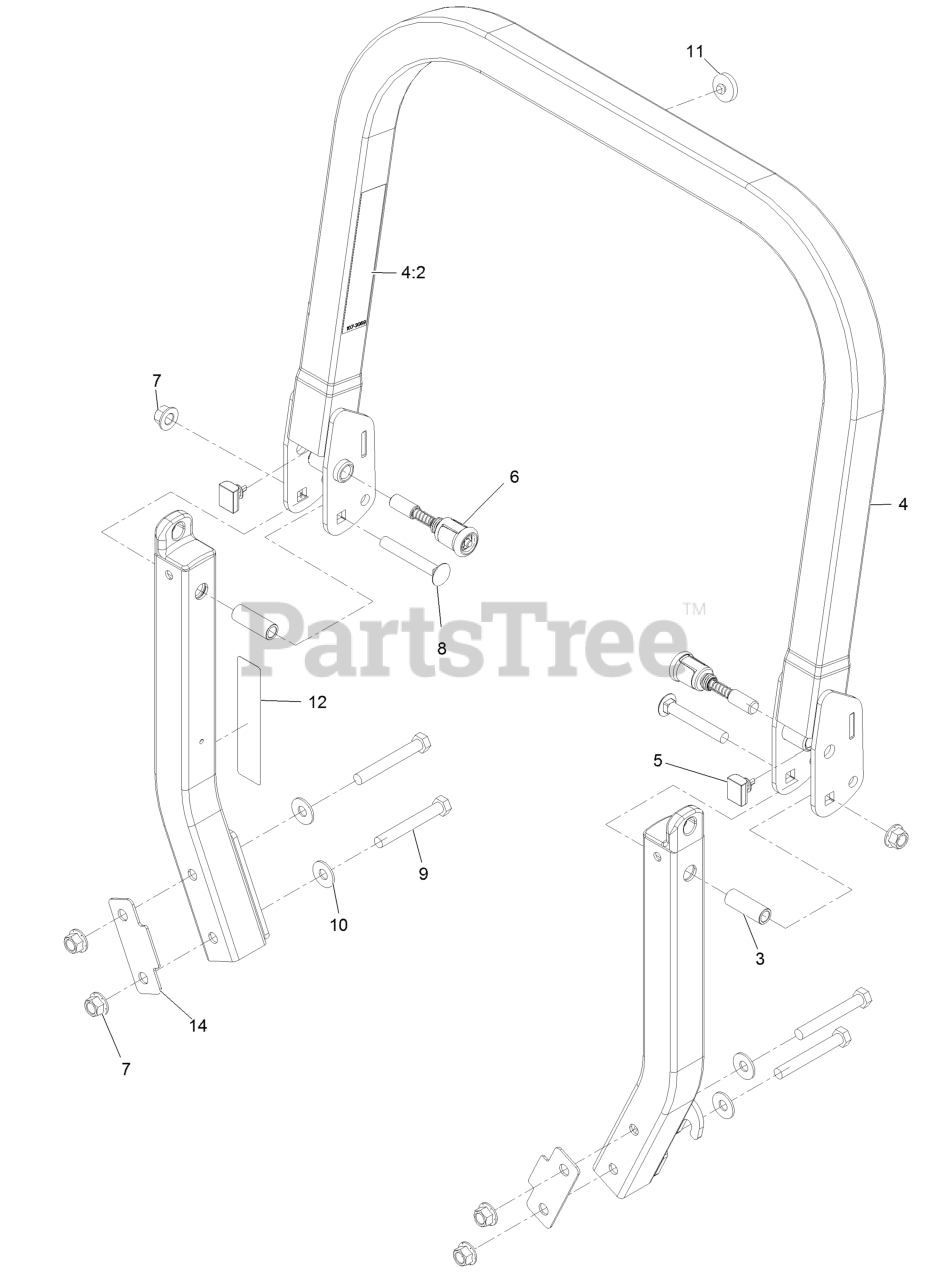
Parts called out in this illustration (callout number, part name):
4	Upper ROPS ASM
4:2	Decal-Warning
5	Bumper-ROPS
6	Pin-Spring
7	Nut-Lock 1/2-13
8	Bolt-Carriage 1/2-13 X 3 1/2
9	Screw-HH
10	Washer, Spring Disc 1/2
11	Bumper-Push-In, Rubber
12	Decal-Caution, Fuel Vent
